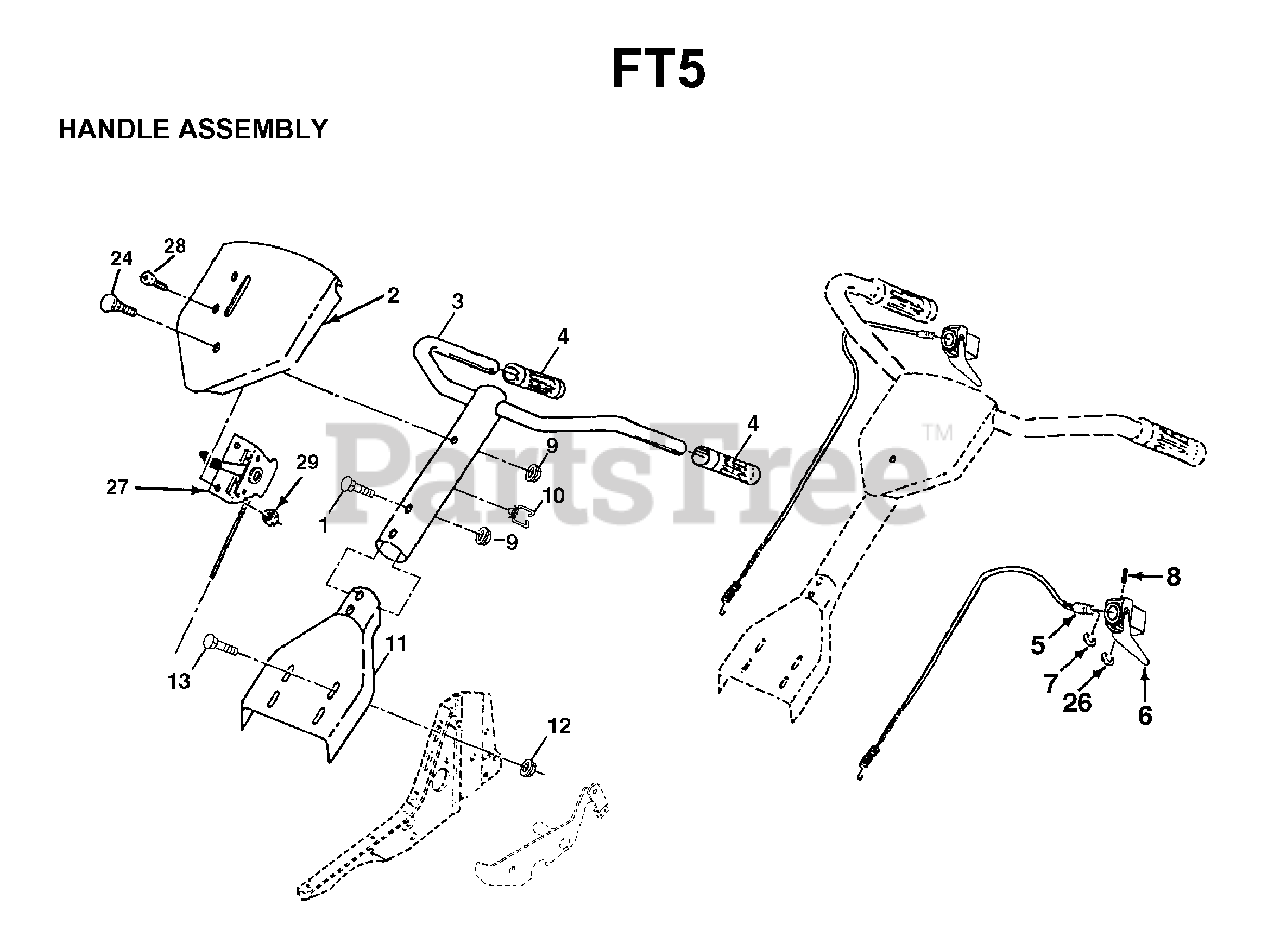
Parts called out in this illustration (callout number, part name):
1	BOLT.5/16-18X2.5
7	RETAINING RING
9	LOCKNUT-FLANGE 5/16-18
12	NUT
13	BOLT.RH.SQNK.5/16
24	BOLT.5/16-18X2.5
26	RETAINING RING
28	SCREW.PNHD.10-24
29	NUT **
